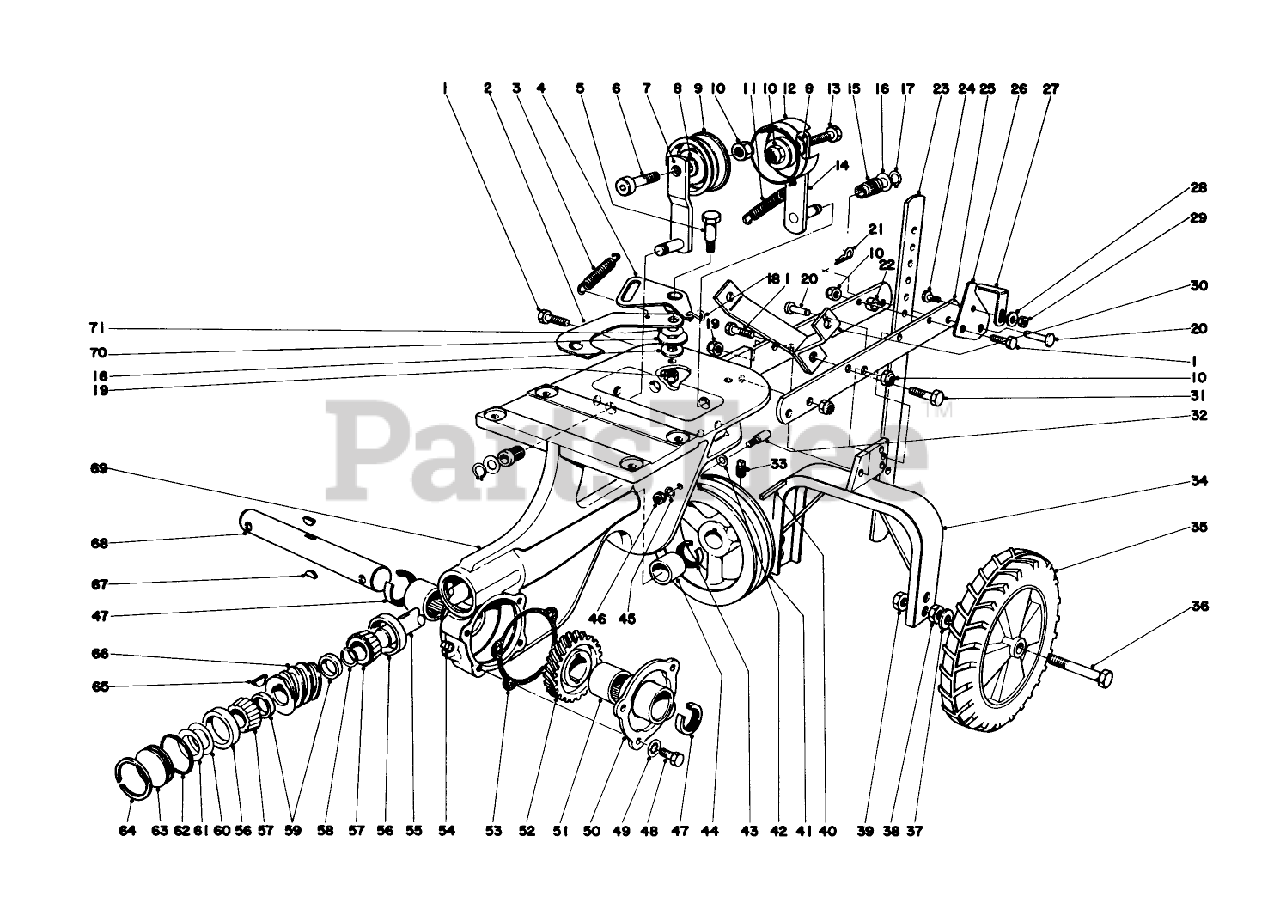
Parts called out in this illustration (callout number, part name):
1	SCREW-HH
2	Rev. Link
3	Spring
4	Bellcrank
5	SCREW-SHOULDER, HH
6	Capscrew
7	IdlerArm
8	WASHER-FLAT
9	PULLEY IDLER
10	NUT-LOCK, CONE
11	Spring
12	IDLER PULLEY
13	SCREW-HH
14	Idler
15	IDLER BRG
16	WASHER-PLAIN
17	RING-RETAINING, EXT
18	S Hook
19	NUT-LOCK, CONE
20	TINE PIN
21	PIN-COTTER, HAIR
22	Spacer
23	DEPTH GAGE
24	SCREW-HH
25	Drawbar
26	Hinge Latch
27	Drag Bar Latch
28	WASHER-FLAT
29	NUT-LOCK, CONE
30	Handle Support
31	SCREW-HH
32	Belt Guide
33	SCREW-SET, HSH
34	Wheel Bracket
35	Wheel
36	SCREW-HH
37	WASHER-FLAT
38	NUT-JAM
39	1/2-13 CONELOCK NUT
40	KEY-SQUARE
41	Pulley
42	WASHER-FLAT
43	SEAL-OIL
44	BUSHING
45	WASHER-LOCK/EXT
46	NUT-JAM
47	SEAL-OIL
48	SCREW-HH
49	WASHER-LOCK
50	Cover
51	Needle Bearing
52	WORM WHEEL
53	GASKET
54	PLUG-PIPE, SQH
55	WORM SHAFT
56	BEARING-ROLLER, CUP
57	BEARING-CONE
58	RETAINER RING
59	SPACER
62	O-RING
64	INTRNL RETAINING RING
65	KEY-WOODRUFF
66	WORM GEAR
67	KEY-WOODRUFF
68	WORM WHEEL SHAFT
69	Chassis
70	WASHER-FLAT
71	7/16 SPRING WASHER
